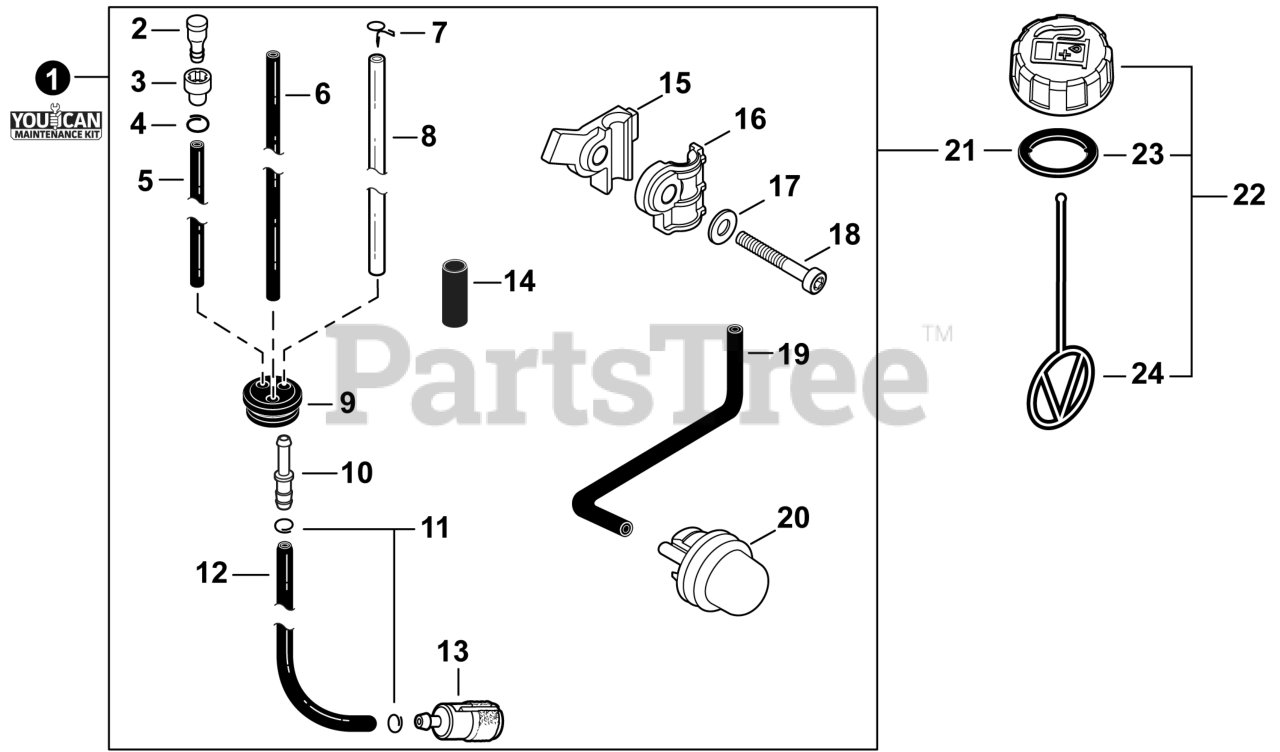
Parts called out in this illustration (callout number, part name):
1	FUEL SYSTEM KIT
2	VENT ASSY
3	HOLDER, VENT
4	CLIP 6.5 MM
5	PIPE, FUEL 3x6x130 BLACK
6	PIPE, FUEL 2.4x5x200 BLACK
7	CLIP, SPRING 5.2
8	PIPE, FUEL 3.5x6x210 CLEAR
9	GROMMET, FUEL
10	CONNECTOR, PIPE 5x3.5
12	PIPE, FUEL 3x5x105L BLACK
13	FILTER, FUEL
14	TUBE, FUEL LINE 16x18xL40
15	CLAMP, LOWER
16	CLAMP, UPPER
17	WASHER, FLAT 5.5x10x0.8
18	BOLT, TORX 5x25
19	PIPE, PURGE 2.4x5x140 BLACK
20	BULB, PURGE
21	GASKET, FUEL CAP
22	CAP ASSY, FUEL
23	GASKET, FUEL CAP
24	CONNECTOR, CAP L= 100 MM
